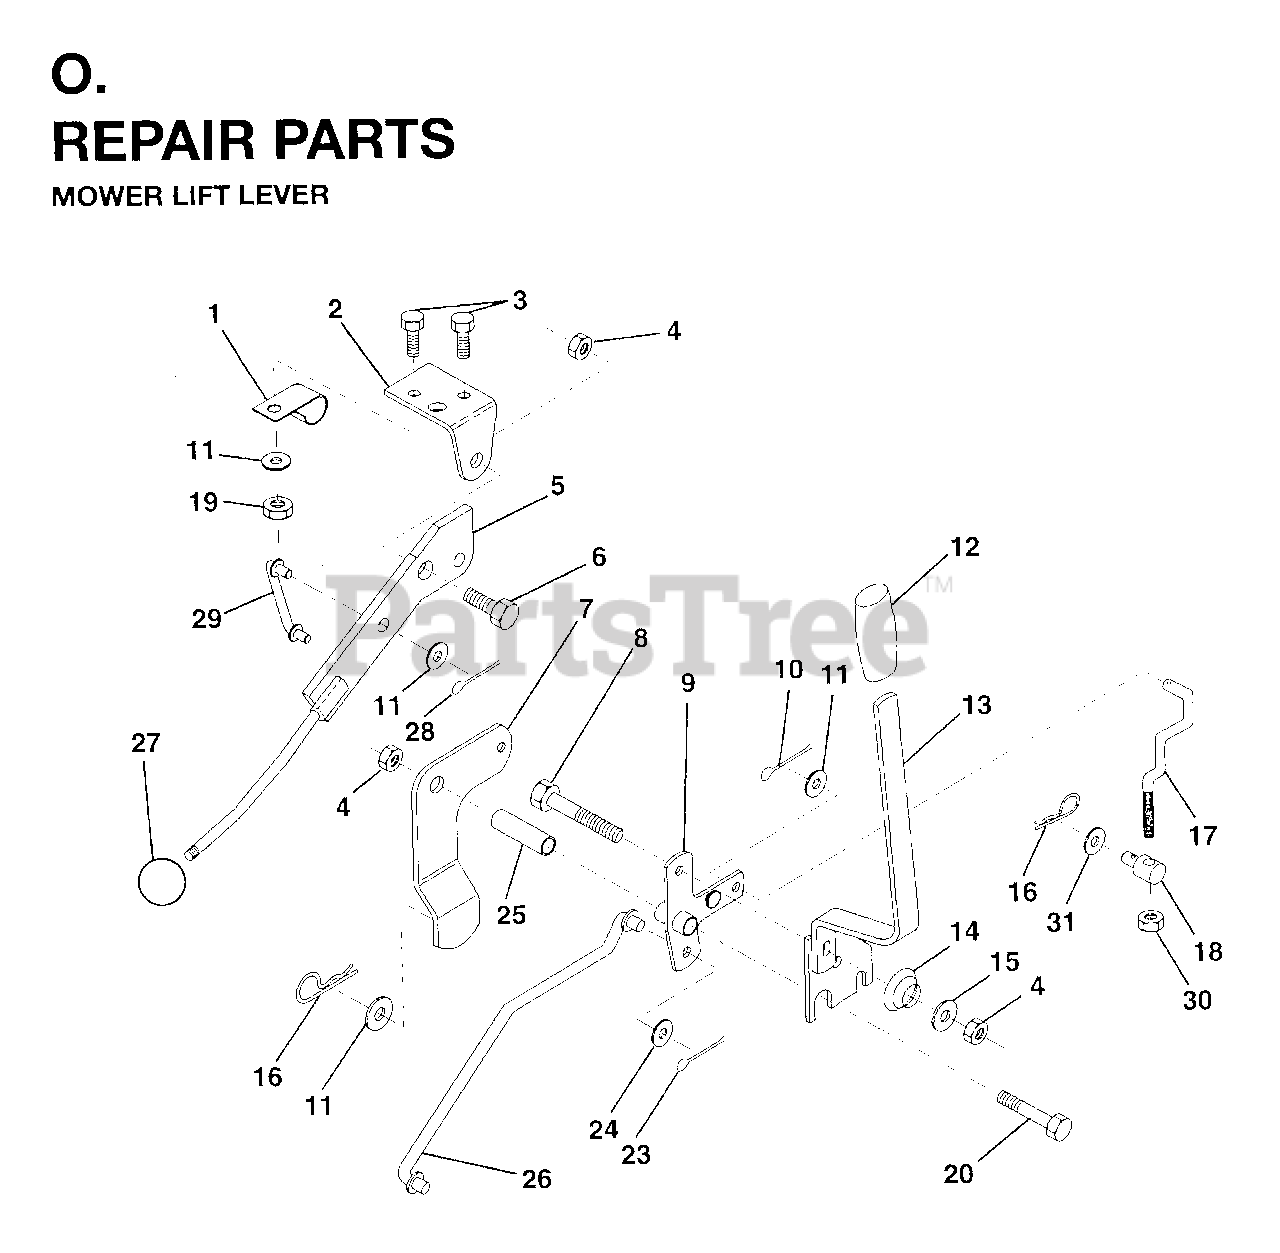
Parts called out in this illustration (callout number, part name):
1	CLIP,INSULATOR
2	BRKT CLUTCH
3	BOLT
4	LOCKNUT
5	CLUTCH LEVER
6	BOLT, SHOULDER LT
7	ASSEMBLY MOWER CLUTCH ARM
9	BELLCRANK,LIFT
10	COTTER PIN
11	WASHER
12	GRIP HANDLE
13	LIFT HANDLE ASSY
14	SPRING COMPRESSIO
15	WASHER
16	SPRING.RETAINER
17	LINK LIFT FRT
19	NUT.CROWNLOCK.1/4
23	PIN COTTER
24	WASHER - M12
25	TUBE SPACER
27	KNOB
28	COTTER PIN
29	LINK MOWER CLUTCH
30	NUT.HEX.3/8-16UNC
